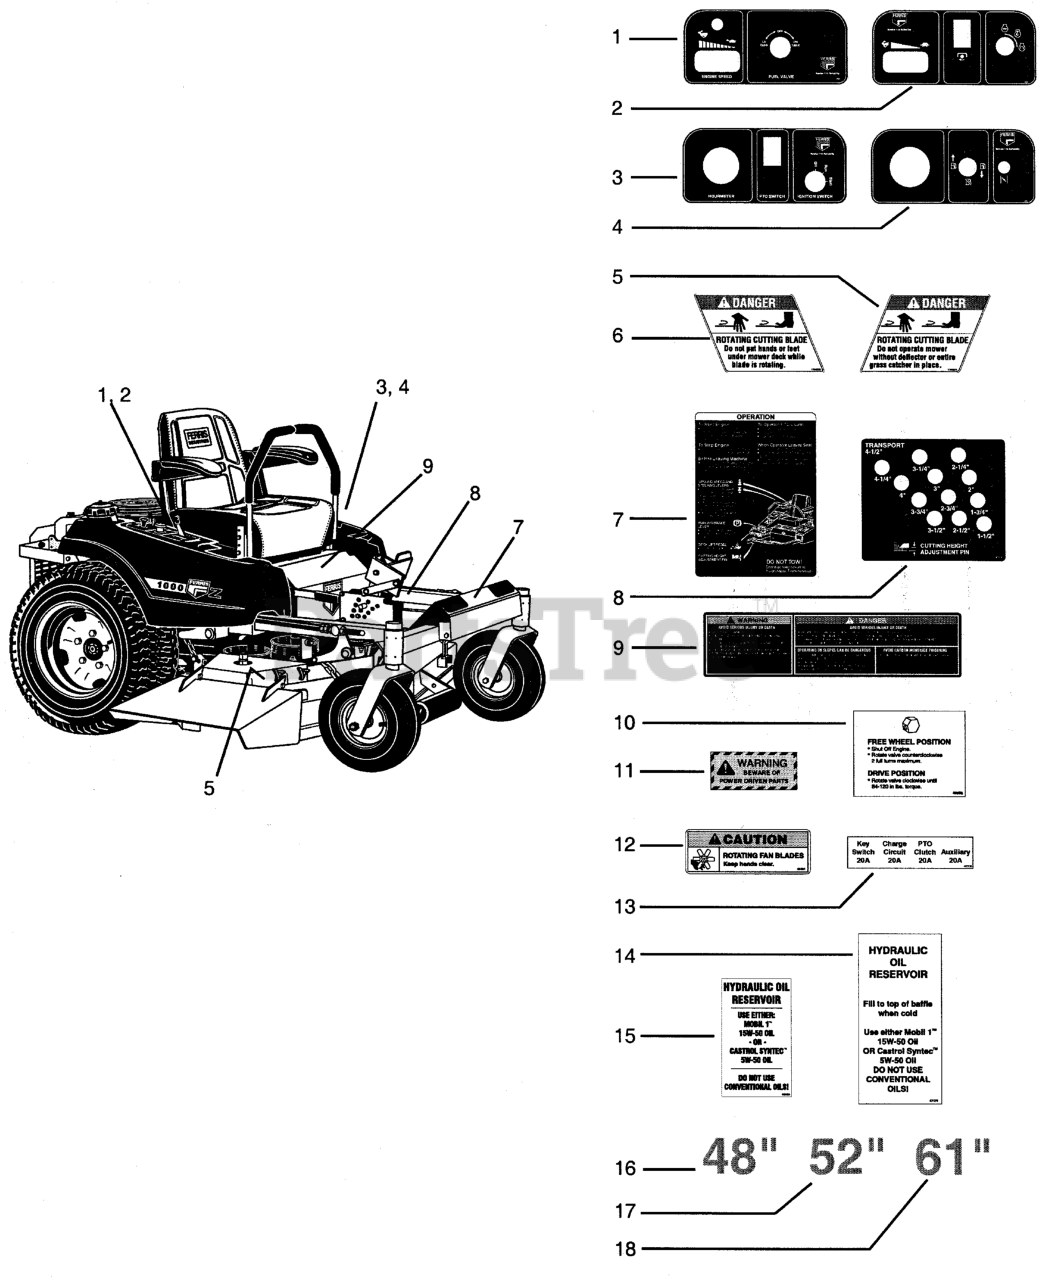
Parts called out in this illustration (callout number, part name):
1	DECAL, Control Panel-RH
2	DECAL, Control Panel-RH
3	DECAL, Control Panel-LH
4	DECAL, Control Panel-LH
5	DECAL, Danger (Chute In Place)
6	DECAL, Danger (Hand Under Deck)
7	DECAL, Operation
8	DECAL, Lift Plate
9	DECAL, Safety/Instruction
10	DECAL, Hydro Release Valve
11	DECAL, Warning
12	DECAL, Caution Fan
13	DECAL, Fuse Location
14	DECAL, Oil Reservoir
15	DECAL, Oil Reservoir
16	DECAL, 48
17	DECAL, 52
18	DECAL, 61"
